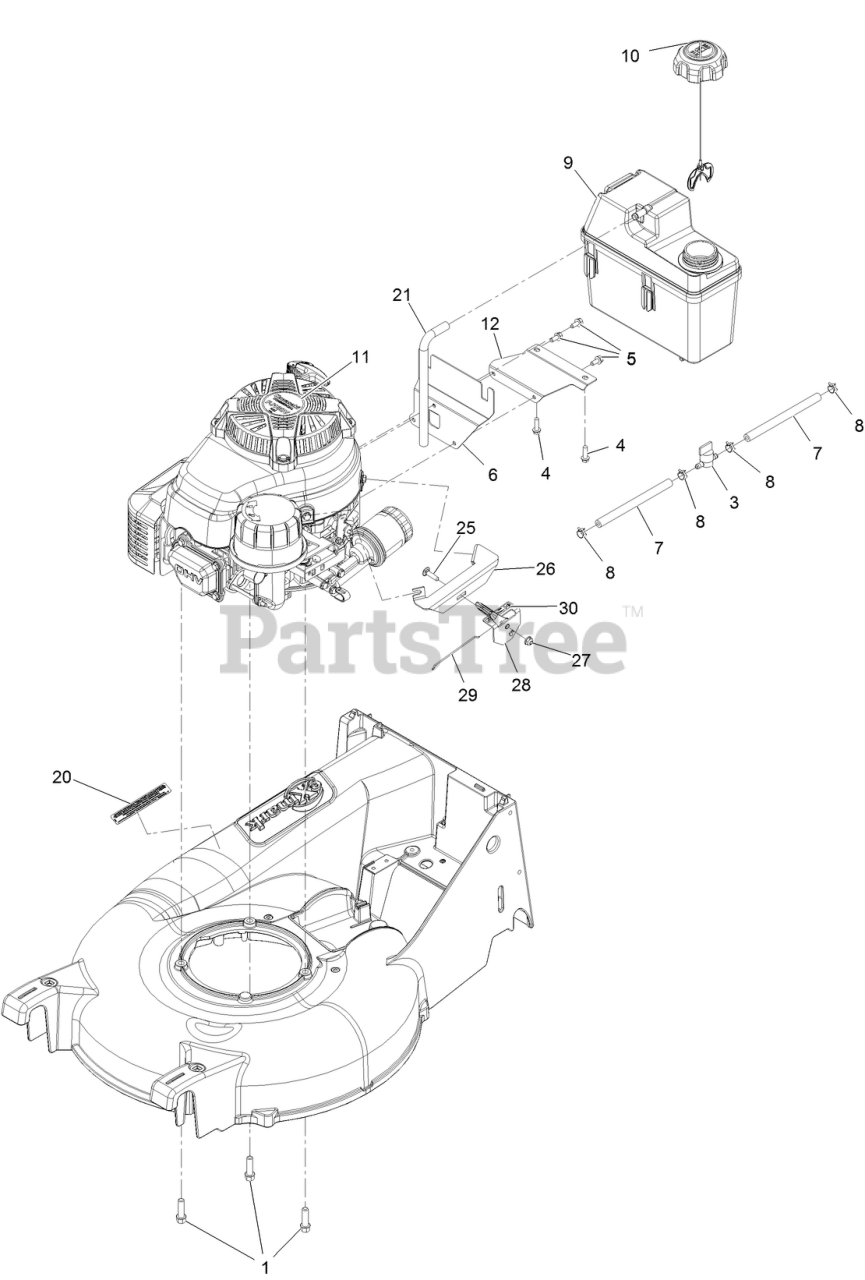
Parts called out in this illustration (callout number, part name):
1	SCREW-TAPTITE
3	VALVE-FUEL
4	SCREW-HWH
5	SCREW-HWH
6	BRACKET-TANK, MOUNTING
7	HOSE-FUEL
8	CLAMP-HOSE
9	TANK-FUEL
10	CAP-FUEL
12	BRACKET-TANK, SUPPORT
20	DECAL-ARRESTOR, SPARK
21	HOSE-VENT, CANISTER
25	SCREW-CARR
26	BRACKET-MOUNT, THROTTLE
28	CONTROL-THROTTLE
29	WIRE-CONTROL
30	DECAL-THROTTLE, CHOKE
